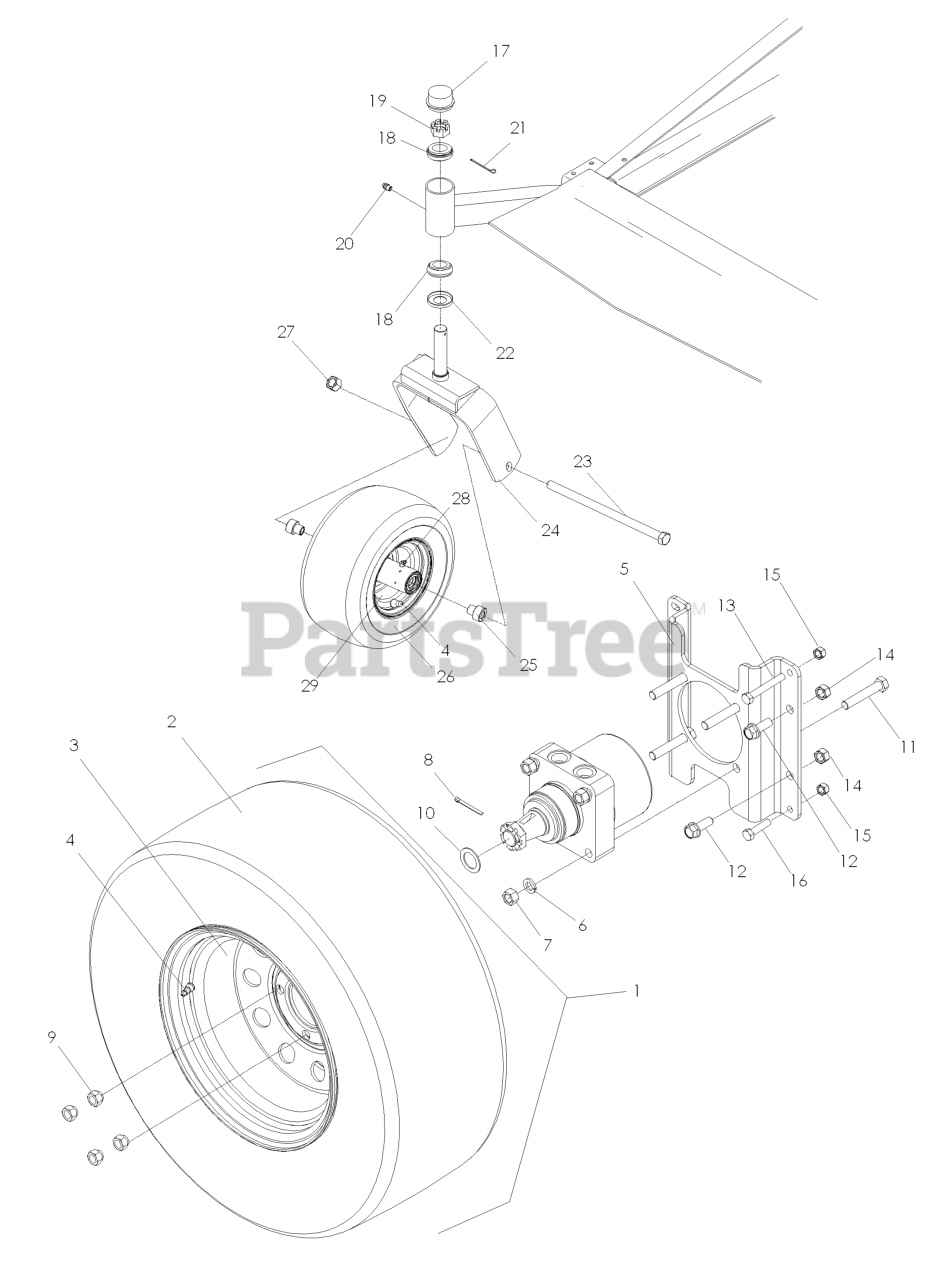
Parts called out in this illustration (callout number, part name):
1	WHEEL/TIRE.ASM.23X9.5-12.GREY
2	TIRE.TURF.MASTER.23X9.5-12
3	RIM.12X7.GRAY.+1".OFFSET.ZTR
4	VALVE STEM TR-412
5	MOUNT, MOTOR, WHEEL - BLK
6	WASHER 1/2" SPLIT LOCK
7	NUT HEX 1/2
8	PIN COTTER 4MM X 45MM
9	LUG NUT 1/2F
10	MACHINE BUSHING
11	HCS 1/2C X 2 3/4
12	HCS 1/2C X 1 1/4 SERRATED HEAD
13	HCS 3/8C X 2 1/4
14	NUT 1/2-13 HEX NYLOC ZD
15	NUT 3/8-16 NYLOC
16	HCS 3/8C X 1 1/4 GR5
17	GREASE CAP
18	TAPERED ROLLER BRG
19	NUT 1"C HEX SLOTTED
20	ZERK
21	COTTER PIN 1/8 X 2
23	HEX SCREW 1/2-13 X 9.5 GR5
24	CASTOR YOKE ORANGE
25	AXLE SPACER
26	FRONT TIRE ASSY
27	NUT 1/2-13 HEX NYLOC ZD
28	ZERK
